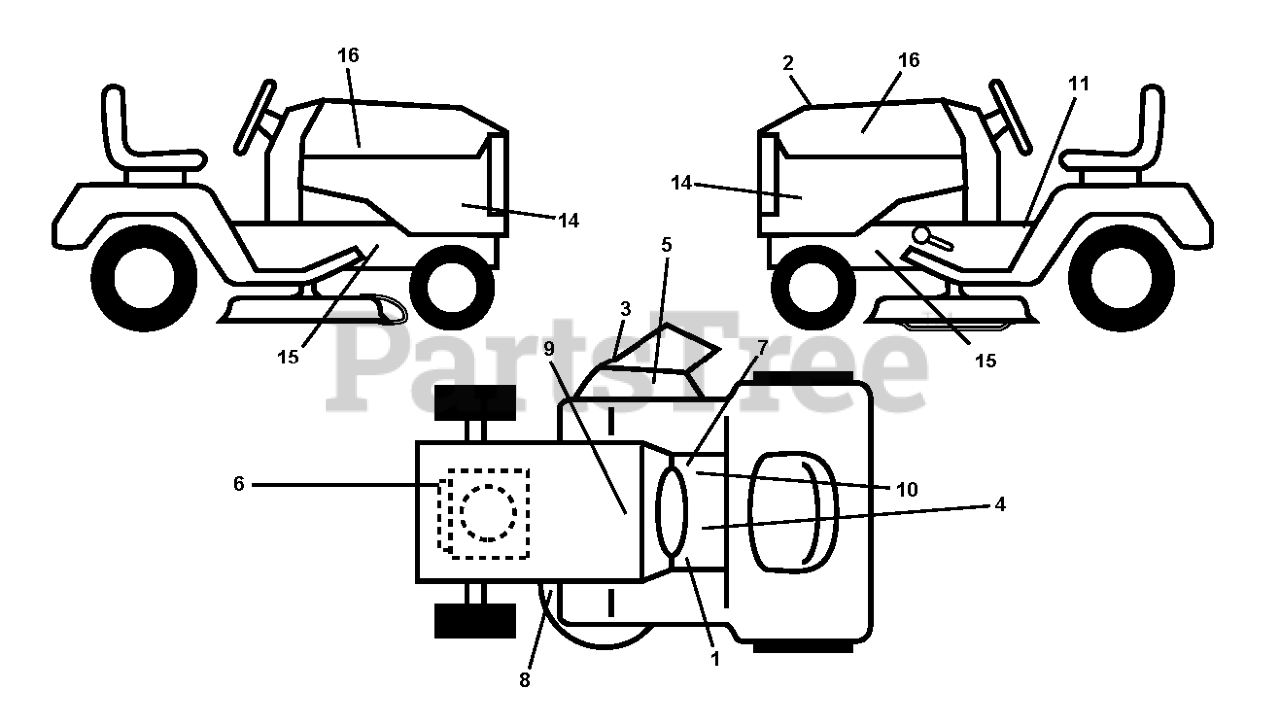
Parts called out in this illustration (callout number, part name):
1	DECAL
3	DECAL, DEFLECT WARNING
4	Decal, Fender 100 DB/CE
5	DECAL.INTERNATIONL.CUTFINGER
6	DECAL
7	DECAL PARK BRAKE
8	DECAL V BELT SCHEMATIC
9	DECAL BTRY SYMBOLS
10	DECAL
11	LABEL
16	RP.DECAL.BADGE.170MM.TEXTLOGO
